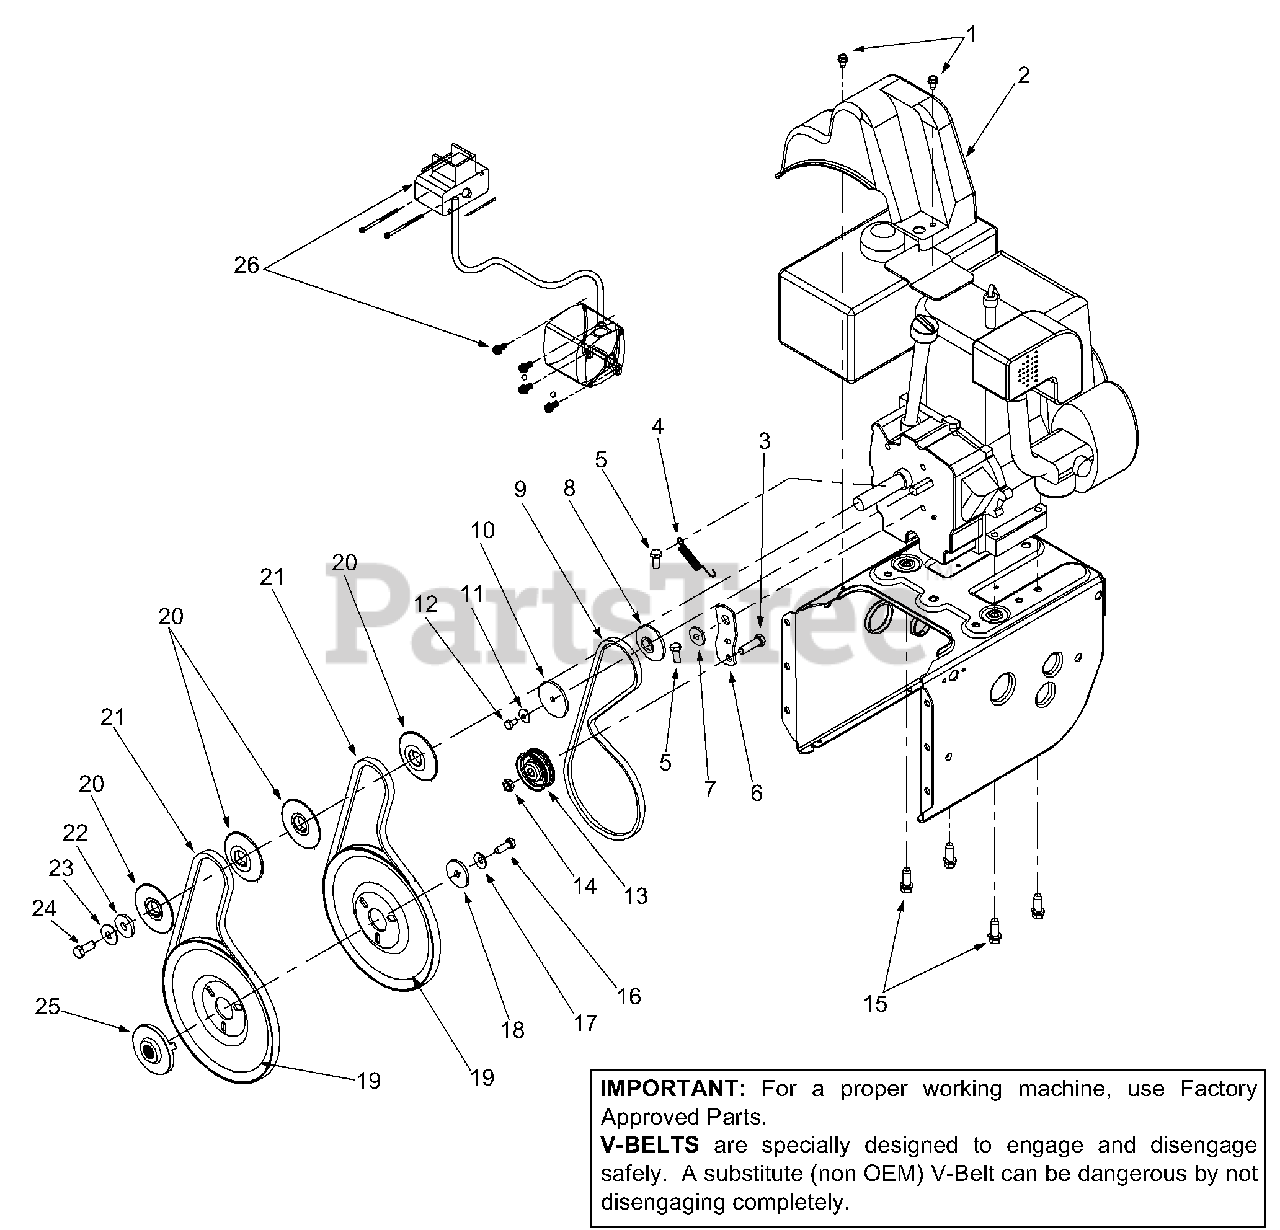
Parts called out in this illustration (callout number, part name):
1	Hex Washer Screw 1/4-20 x .50
2	Belt Cover
3	Hex Cap Screw 3/8-16 x 1.25
4	Spring Extension
5	Hex Screw 5/16-24 x .75
8	Pulley Half
9	Belt
10	Pulley Half
11	Bell Washer
12	Hex Cap Screw
13	Flat Idler
14	Lock Jam Nut 3/8-16
15	Hex Washer Screw 3/8-16 x 1.0
16	Hex Lock Screw 5/16-24 x .875
17	Bell Washer .340 ID x .872 OD
18	Flat Washer .341 ID x .50 OD
19	Pulley Auger
20	Pulley Half
21	V-Belt
22	Flat Washer
23	Bell Washer .39 ID x 1.13 OD
24	Hex Cap Screw 3/8-24 x .875
25	Pulley Adapter
26	Electric Start
